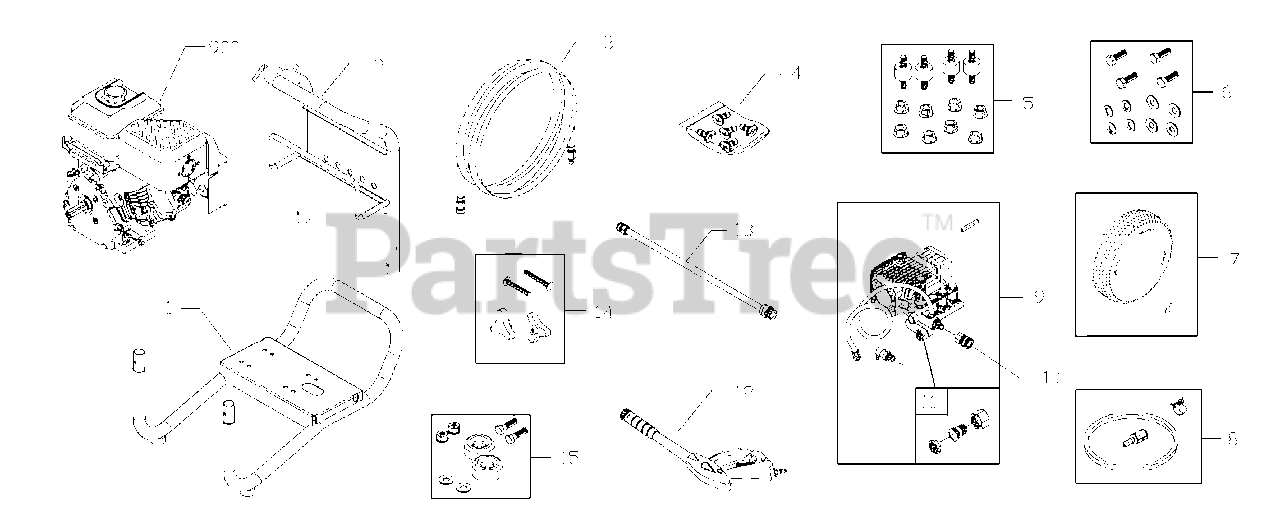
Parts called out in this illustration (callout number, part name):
1	BASE
2	HANDLE
4	KIT, QC Nozzles
5	KIT, Vibration Mount
6	KIT, Hardware, Pump Mounting
10	FITTING
11	ADAPTER, Garden Hose
12	GUN
13	EXTENSION, QC
14	KIT, Hardware, Handle
15	KIT, Vibration Mount
900	**ENGINE
